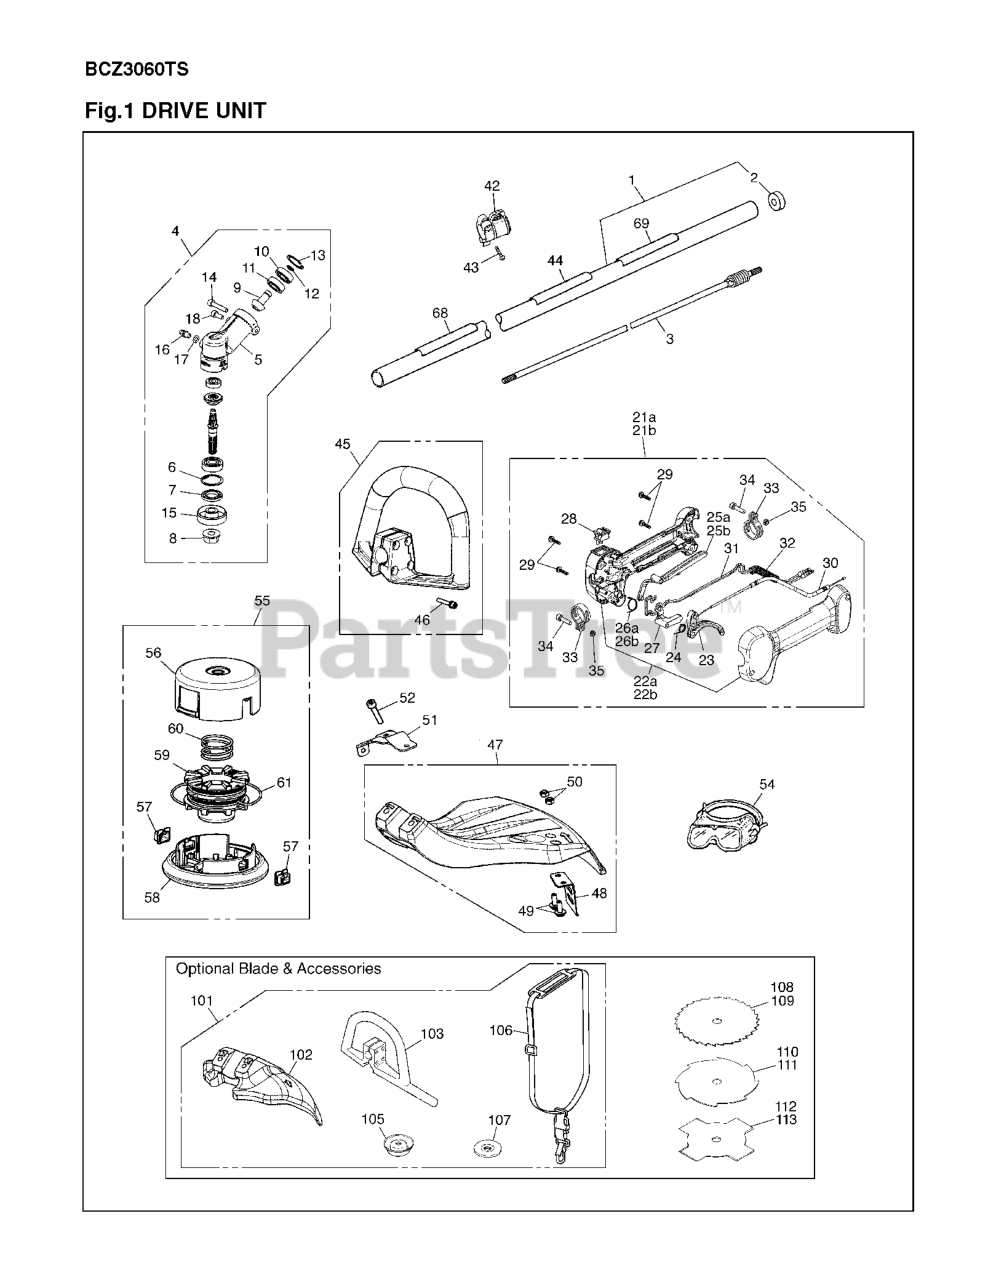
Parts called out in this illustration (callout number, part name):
1	PIPE COMP
3	DRIVESHAFT
4	GEARCASE ASSY
5	GEARCASE
6	RING,SNAP M26x1.2 RP-318013340
11	BALL BEARING
14	BOLT TORX
15	HOLDER(A)
18	BOLT, TORX
21	GRIP ASSY
22	GRIP HALF SET
23	LEVER, THROTTLE
24	SPRING, THROTTLE
25	LEVER FOR GRIP (RPLS -0600)
25	LEVER, SAFETY
26	SPRING JOINT
26	SPRING
27	LEVER JOINT
31	CORD - C
35	NUT
42	HANGER COMP.
44	LABEL CAUTON FOR BC
45	HANDLE ASSY. (RPLS T319514001)
47	GUARD ASSY
52	BOLT, TORX
54	GOGGLExxx (RPLS
55	4" TAP TRIMMER HEAD PT104
56	CASE (RPL T318915112)
58	COVER (RPLS T318915131)
59	HOLDER, CORD (RPLS T318915141)
61	CORD
69	NAME LABEL BCZ3060TS
101	BLADE KIT FOR BCZ2460
103	HANDLE-ASSY
106	STRAP ASSY
107	HOLDER (B)
108	Brushcutter Blade, 22 Tooth 9"
109	Brushcutter Blade, 24 Tooth 9"
110	BLADE, 8
111	Brushcutter Blade, 8 Tooth 9"
112	BLADE, 8
113	Brushcutter Blade, 4 Tooth 9"
